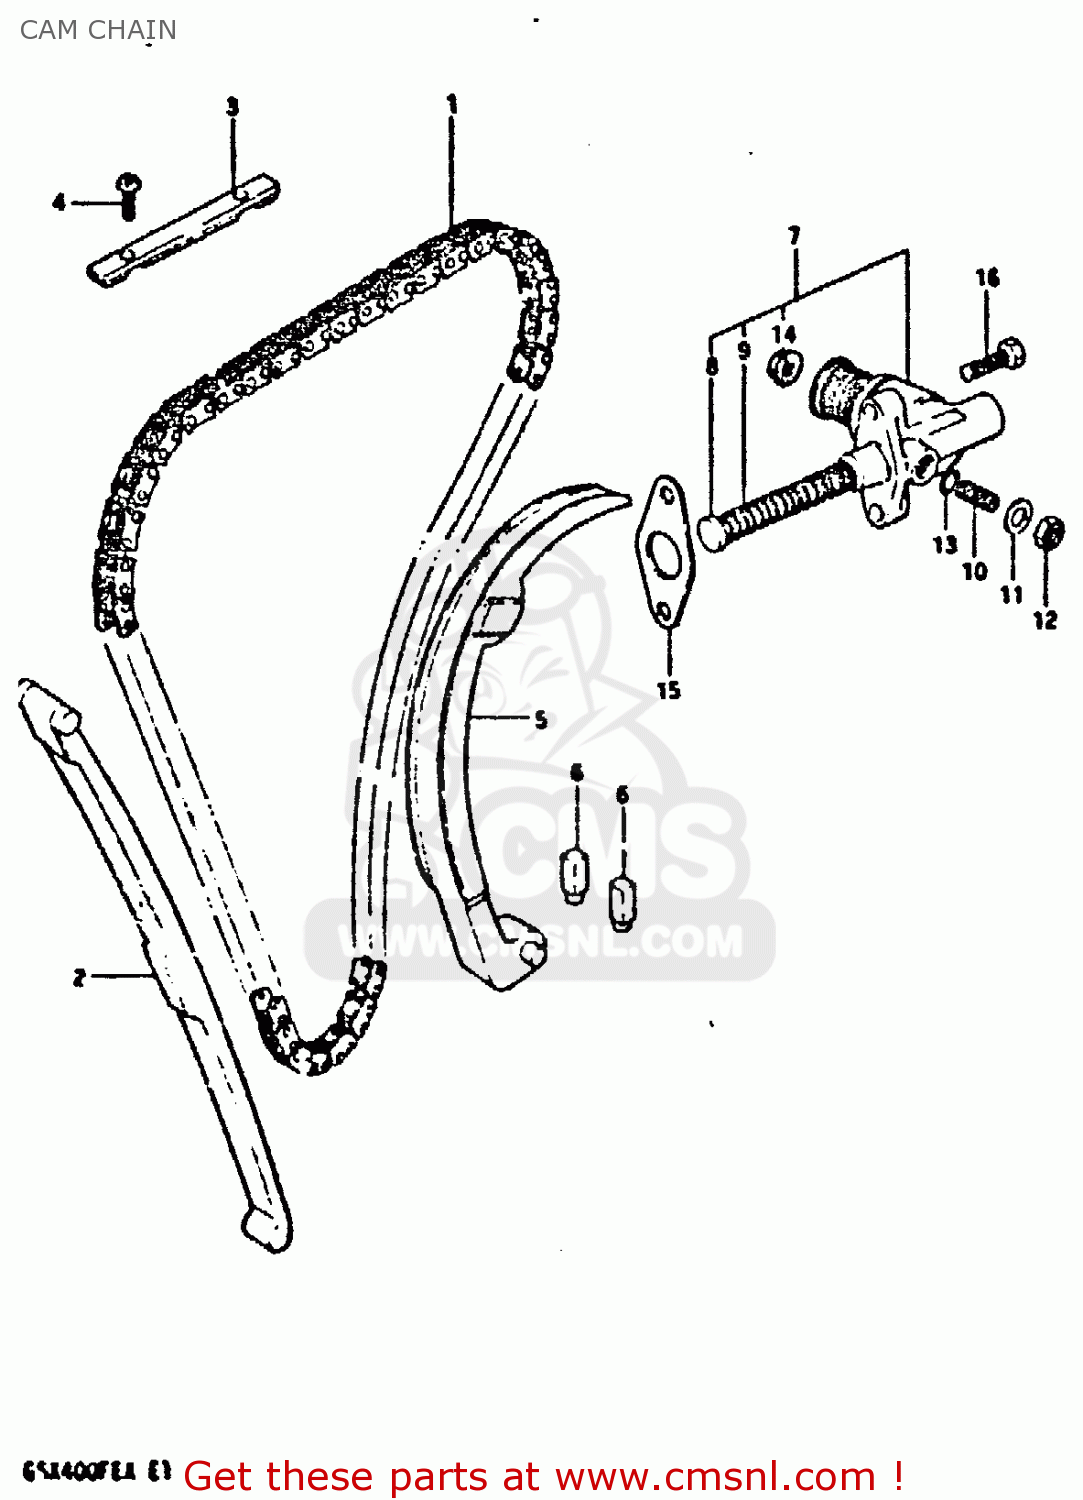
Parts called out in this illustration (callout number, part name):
1	CHAIN, CAM SHAFT DRIVE
2	GUIDE,CAM CHAIN NO.1
3	GUIDE,CAM CHAIN NO.2
4	SCREW
5	TENSIONER,CAM CHAIN
6	CUSHION,CAM CHAIN TENSIONER
7	ADJUSTER ASSY, TENSIONER
8	PUSH ROD
9	SPRING
10	SCREW
11	E RING 8MM
12	NUT
13	O-RING
14	NUT
15	GASKET,TENSIONER ADJUSTER (MCA)
16	SCREW (6X25)
